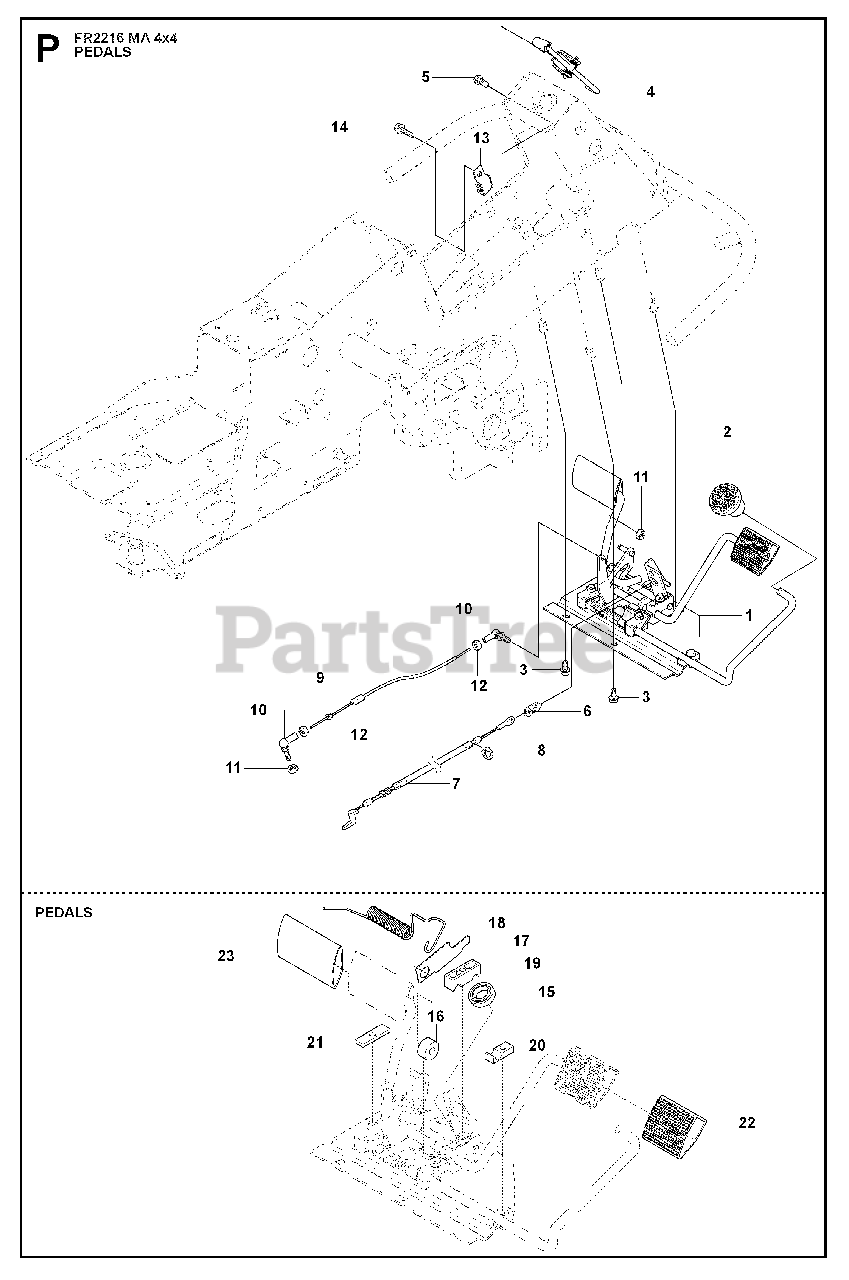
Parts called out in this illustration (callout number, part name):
1	PEDAL ASSEMBLY
2	KNOB
4	BRAKE LEVER ASSY
7	RP WIRE
9	%WIRE
10	CONNECTOR
11	LOCKNUT M5
15	BALL BEARING 6002-2RS1
16	ROLLER
17	PLATE
18	SPRING
19	PEDAL SHAFT CLAMP
20	SUPPORT
21	PLATE
22	PEDAL RUBBER
23	PEDAL RUBBER, SF
